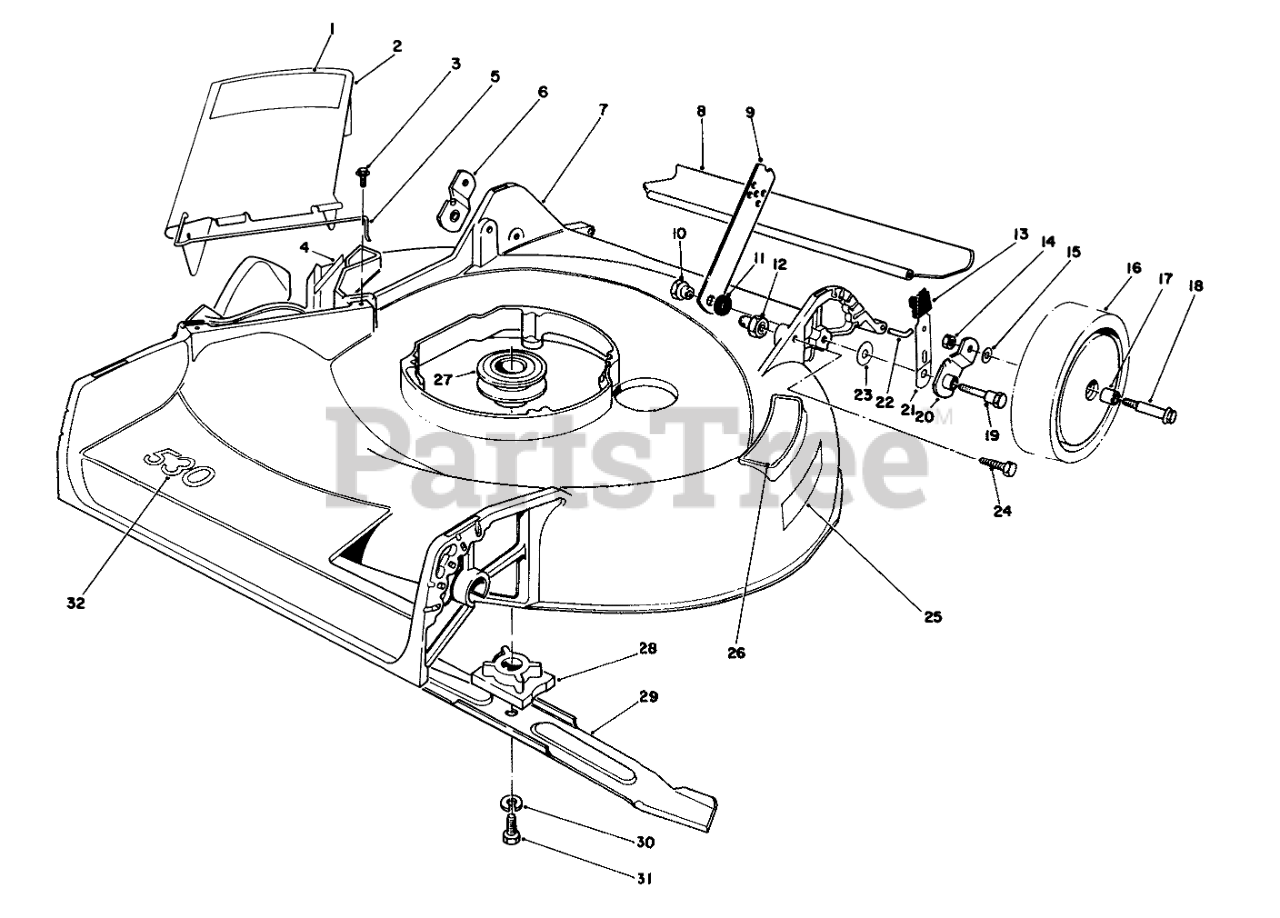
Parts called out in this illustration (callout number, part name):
1	Decal-Danger(French)
2	Deflector Assembly Ref. #1 & 5)
3	SCREW-HWH
4	Decal-Danger
5	SPRING HINGE
6	Pivot Arm
7	Housing
8	REAR SAFETY SHIELD 21
9	HANDLE LATCH
10	HANDLE PIVOT NUT
11	SPACER
12	HANDLE PIVOT NUT
13	KNOB-ARM
14	NUT-LOCK
15	WASHER
16	Wheel & Tire (Incl. Ref. #17)
17	BUSHING
18	WHEEL BOLT
19	PIVOT SCREW
20	Pivot Arm
21	SPRING ARM ASM
22	SHIELD ROD
23	WASHER-PIVOT
24	SCREW-HH
25	Decal-Step
26	STEP PAD DECAL
27	Pulley
28	BLADE RETAINER
29	Blade
30	WASHER-LOCK
31	SCREW-HH
32	Decal-530
